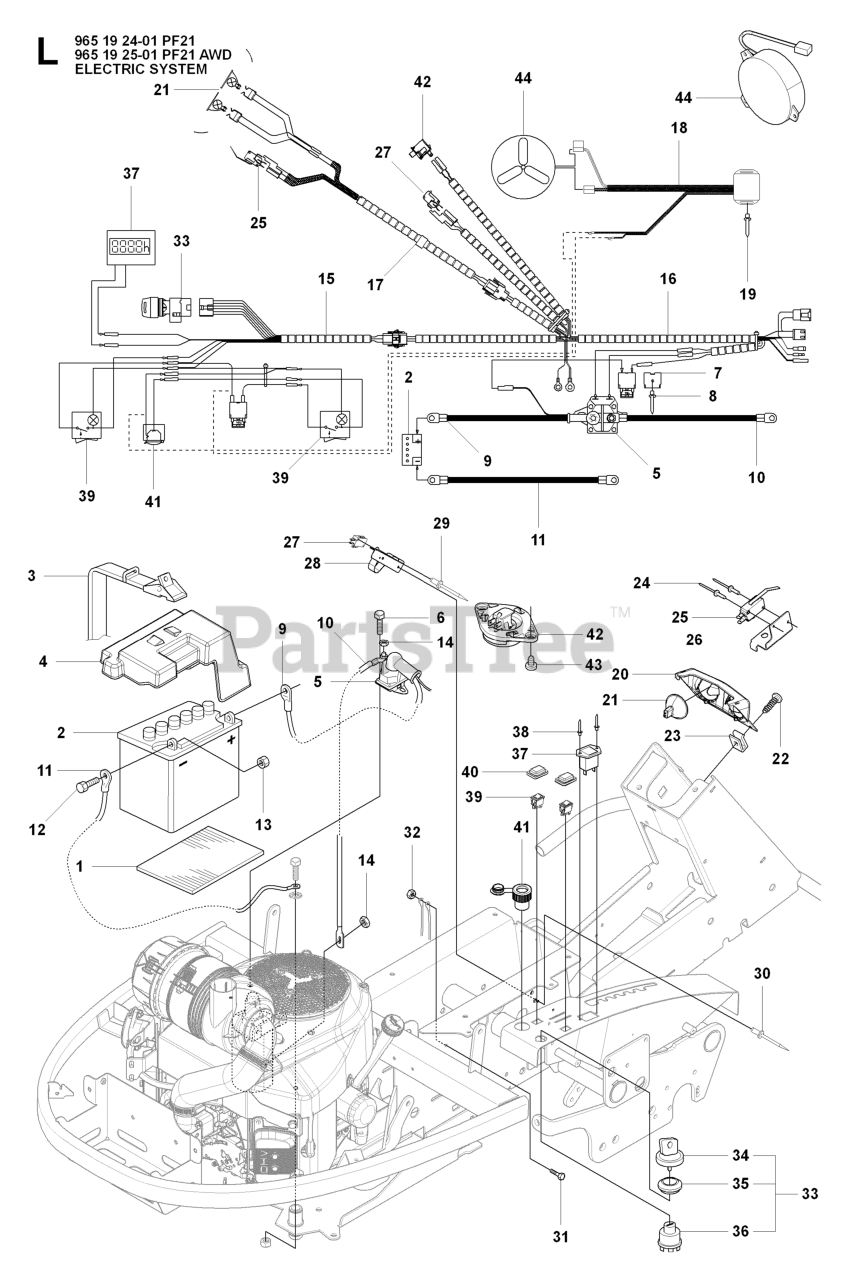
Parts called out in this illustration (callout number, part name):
2	BATTERY - DRY
15	WIRING CONTROL PANEL
25	RP MICRO SWITCH
27	%BRAKER
37	HOUR METER
42	ANTI-START SWITCH CPL
43	SCREW
